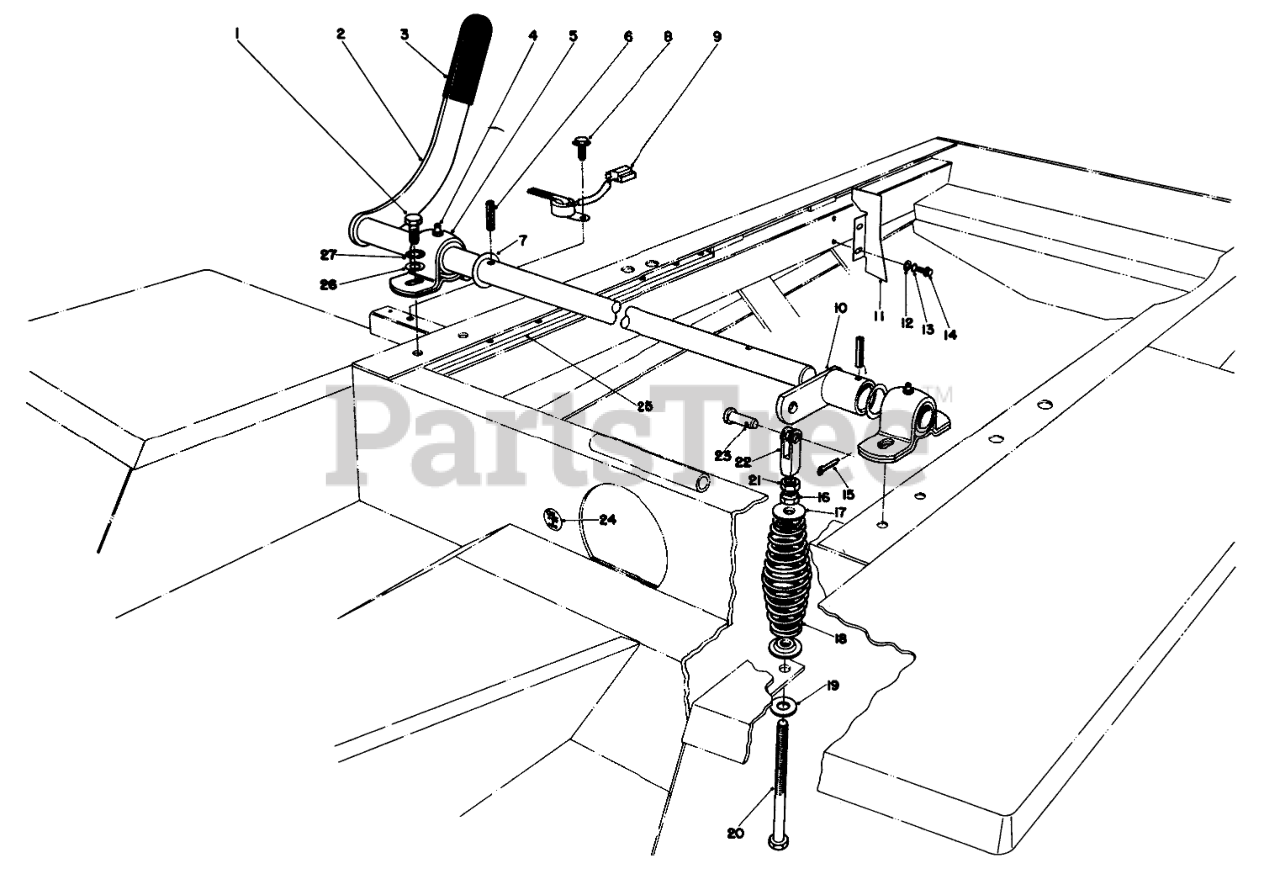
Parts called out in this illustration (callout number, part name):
1	SCREW-HH
2	P.T.0. Lever
3	GRIP-HANDLE
4	FITTING-GREASE
5	BEARING
6	PIN-SPRING
7	THRUST WASHER
8	SCREW-THD FRM,HWH
9	SWITCH ARM
10	Engagement Arm
11	Shield-Heat
12	WASHER-PLAIN
13	WASHER-LOCK
14	SCREW-HWHTF
15	PIN-COTTER
16	NUT-HEX
17	SPRING RET TOP
18	COMP SPRING
19	WASHER
20	SCREW-ADJUSTING
21	NUT-HJ
22	Yoke
23	PIN-CLEVIS
24	OIL DECAL
25	Bar Frame Rail
26	WASHER-FLAT
27	WASHER-LOCK
